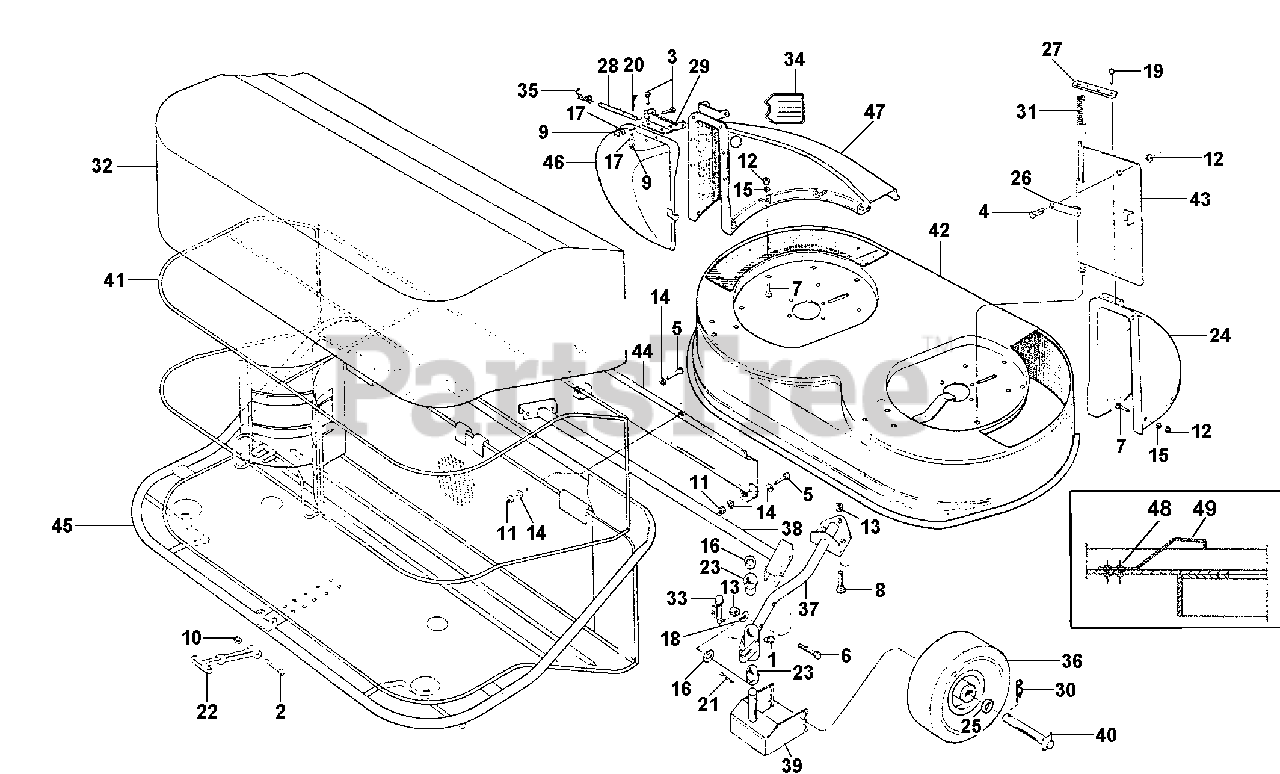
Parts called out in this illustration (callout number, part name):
1	LUBRICATOR M10
2	SCREW TE M4X40
3	SCREW M5X10
4	SCREW TE M6X14
5	SCREW M5X16
6	SCREW TE M8X45
7	SCREW M6X20
8	SCREW TTQ M8X20
11	NUT, SELF LOCKING M5
12	NUT, SELF LOCKING M6
13	NUT, SELF LOCKING M8
14	WASHER, FLAT 5.3
15	WASHER, FLAT 6.4
16	WASHER, FLAT 21
17	SUPER WASHER
18	WASHER, LOCK 8.4
19	SCREW 6.3X19
20	COTTER PIN A 3X15
21	PIN, COTTER A 4X30
22	RUBBER HANDLE
24	LEFT HAND CONVEYOR
32	GRASS CATCHER BAG
35	DEFLECTOR SPRING
36	COMPLETE WHEEL 3.00-4
37	LONG SUPPORT
42	LAWN MOWER CRANKCASE
43	LEFT HAND FLAP
44	REAR PROTECTION
45	BAG FRAME BOTTOM
48	RIVET M3.8X12
